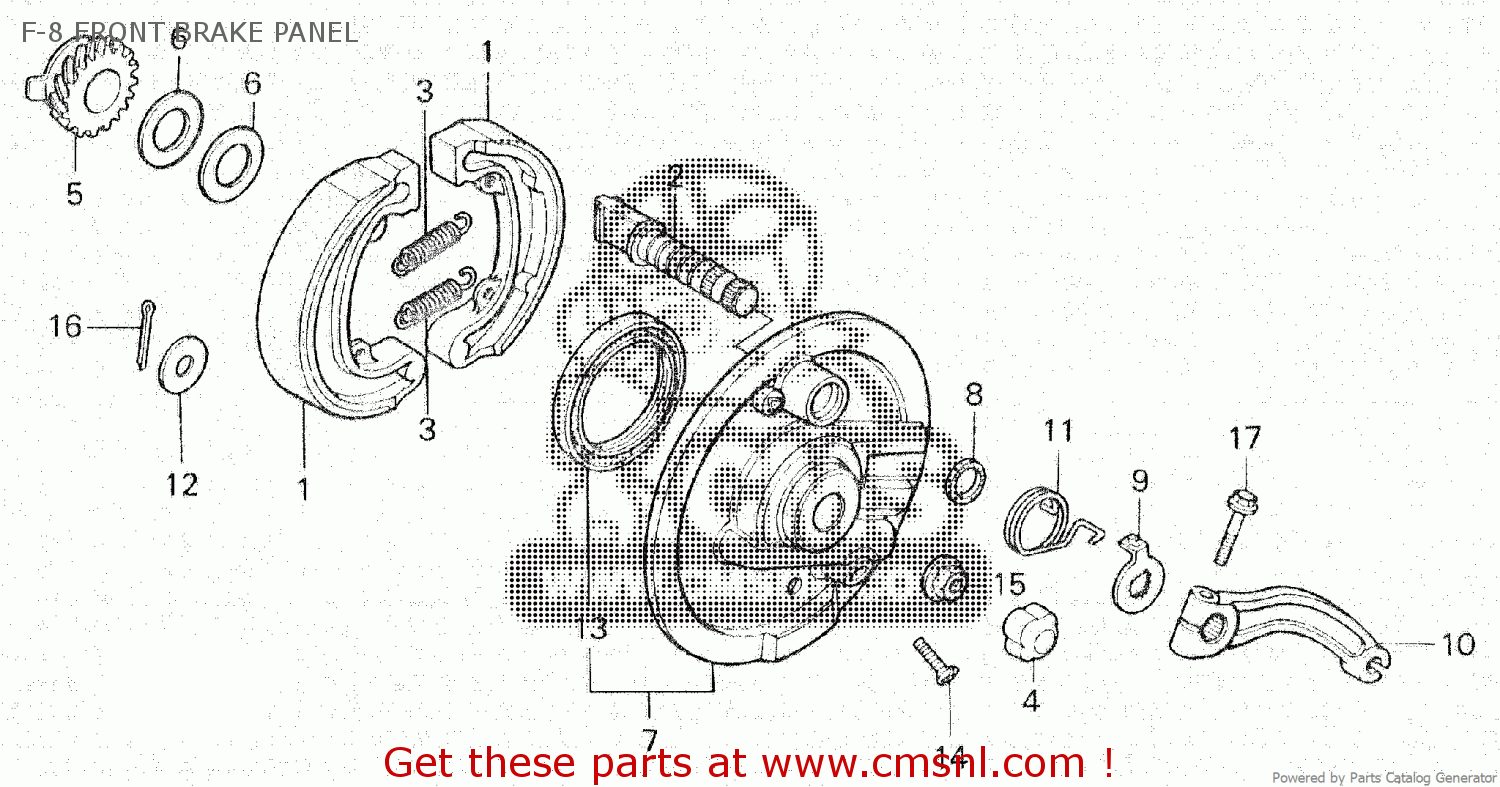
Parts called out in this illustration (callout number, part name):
1	SHOE,REAR BRAKE (MCA)
2	CAM,RR.BRAKE
3	SPRING BRAKE SHOE
4	CAP, AXLE NUT
5	GEAR SPEEDOMETER
6	WASHER,SPDMT.GEAR
7	PANEL SUB BRAKE
8	DUST-SEAL, BRAKE
9	INDICATER BRAKE
10	ARM,FR.BRAKE
11	SPG BRAKE ARM RTN
12	WASHER, HANDLE
13	OIL SEAL,47X60X7
14	SCREW,OVAL,5X16
15	NUT, FLANGE, 12MM
16	PIN COTTER 2.0MM
17	BOLT,FLANGE,6X28
